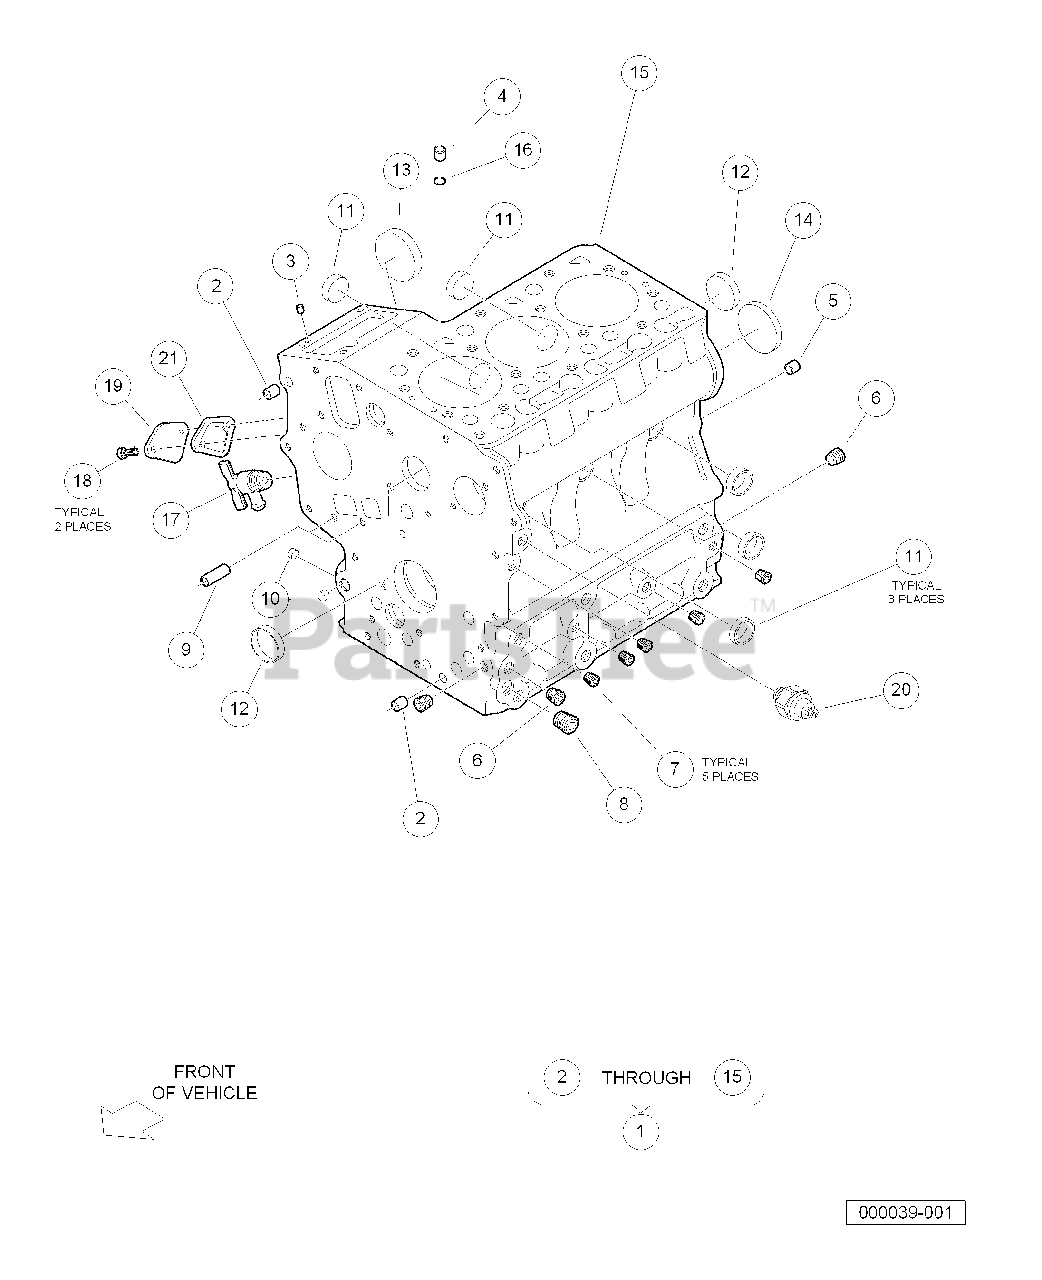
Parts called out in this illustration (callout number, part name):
1	Engine Block
2	Pin, Pipe, Dia 8 X 14
3	Pin, Straight, Dia 5 X 10
4	Pin, Pipe, Dia 7 X 14
5	Pin, Straight, Dia 8 X 16
6	Plug, 1/8"
7	Plug, 3/32"
8	Plug, 1/4"
9	Pin, Pipe, Dia 8 X 11
10	Cap, Sealing, Small
11	Cap, Sealing, Med
12	Cap, Sealing, Large
13	Cover, Fuel Camshaft
14	Plug, Expansion
15	Block, Engine
16	O Ring, 8 X 7
17	Cock, Drain
18	Bolt, M6 X 1 X 20
19	Plate, Engine Block
20	Switch, Oil Pressure
21	Gasket, Fuel Pump, D722
